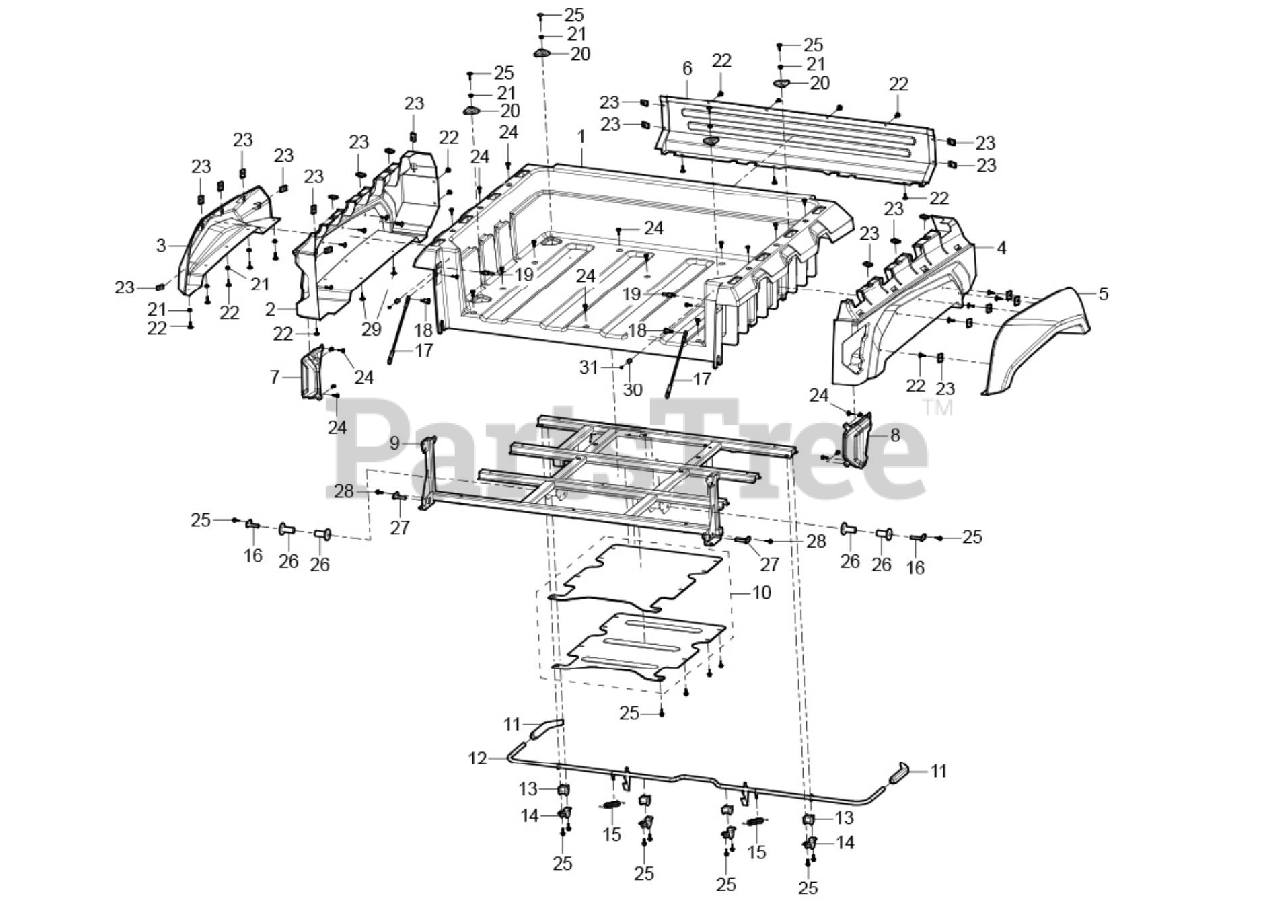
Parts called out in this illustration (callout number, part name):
1	CARGO BED
2	SIDE PANEL LEFT, RED
2	SIDE PANEL LEFT, YELLOW
2	SIDE PANEL LEFT, BLUE
2	SIDE PANEL LEFT, BLACK
2	SIDE PANEL LEFT, CAMO
3	FENDER - REAR LEFT TOP
4	SIDE PANEL RIGHT, RED
4	SIDE PANEL RIGHT, YELLOW
4	SIDE PANEL RIGHT, BLUE
4	SIDE PANEL RIGHT, BLACK
4	SIDE PANEL RIGHT, CAMO
5	FENDER - REAR RIGHT TOP
6	CARGO BED FRONT PANEL
7	TAIL BRAKE LIGHT ASSEMBLY - REAR LEFT
8	TAIL BRAKE LIGHT ASSEMBLY - REAR RIGHT
9	CARGO BED FRAME
10	HEAT PROTECTOR - CARGO BED
11	RELEASE LEVER GRIP
12	CARGO BED RELEASE LEVER KIT
13	RELEASE LEVER CUSHION
15	Tension Spring 2x 14x40
16	PIN - CARGO BED KIT
17	CABLE - CARGO BED DOOR J
18	BLOT HExAGON SOCKET SHOULDER M8x15-10x14.5
19	BLOT HExAGON SOCKET SHOULDER M8x15-10x10-53
20	HOOK - CARGO BED
21	HExAGON FLANGE HEAD NUT M6
22	Cross Large Plate Head Screw M6x16
23	CLAMP NUT M6x6
24	Socket Hex Flat Head Bolt M6x16
25	Hexagon Flange Bolt M6x16
26	BUSHING - PLASTIC 12x18
27	HINGE STRAP PLATED
28	BOLT HExAGON FLANGE HEAD M8x12
29	SCREW - CROSS HEAD SELF DRILLING ST4.8x16
30	CARGO DOOR SHOCK ABSORBER
31	SCREW CROSS HEAD SELF DRILLING ST4.2x13
